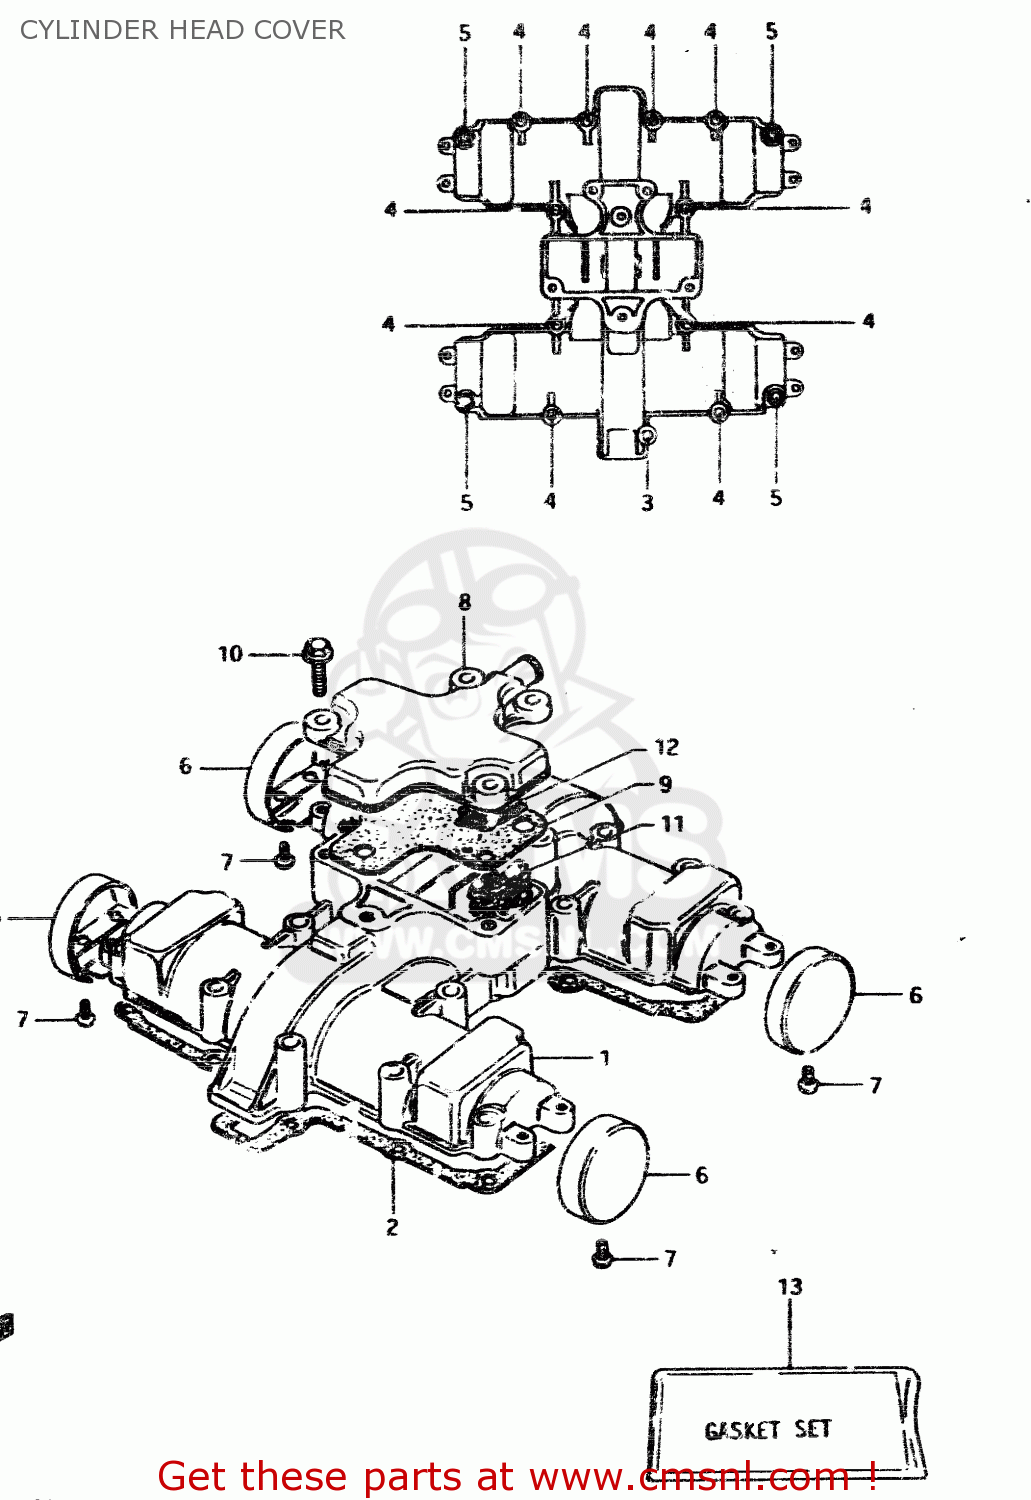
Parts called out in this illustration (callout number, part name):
1	COVER,CYLINDER HEAD
2	GASKET,CYLINDER HEAD COVER (MCA)
3	BOLT (6X45)
4	BOLT (6X40)
5	BOLT 6X30
6	CAP,CYLINDER HEAD COVER
7	SCREW
8	COVER,BREATHER
9	GASKET (MCA)
10	BOLT
11	COVER,BREATHER
12	SEPARATOR,OIL BREATHER
13	GASKET SET
